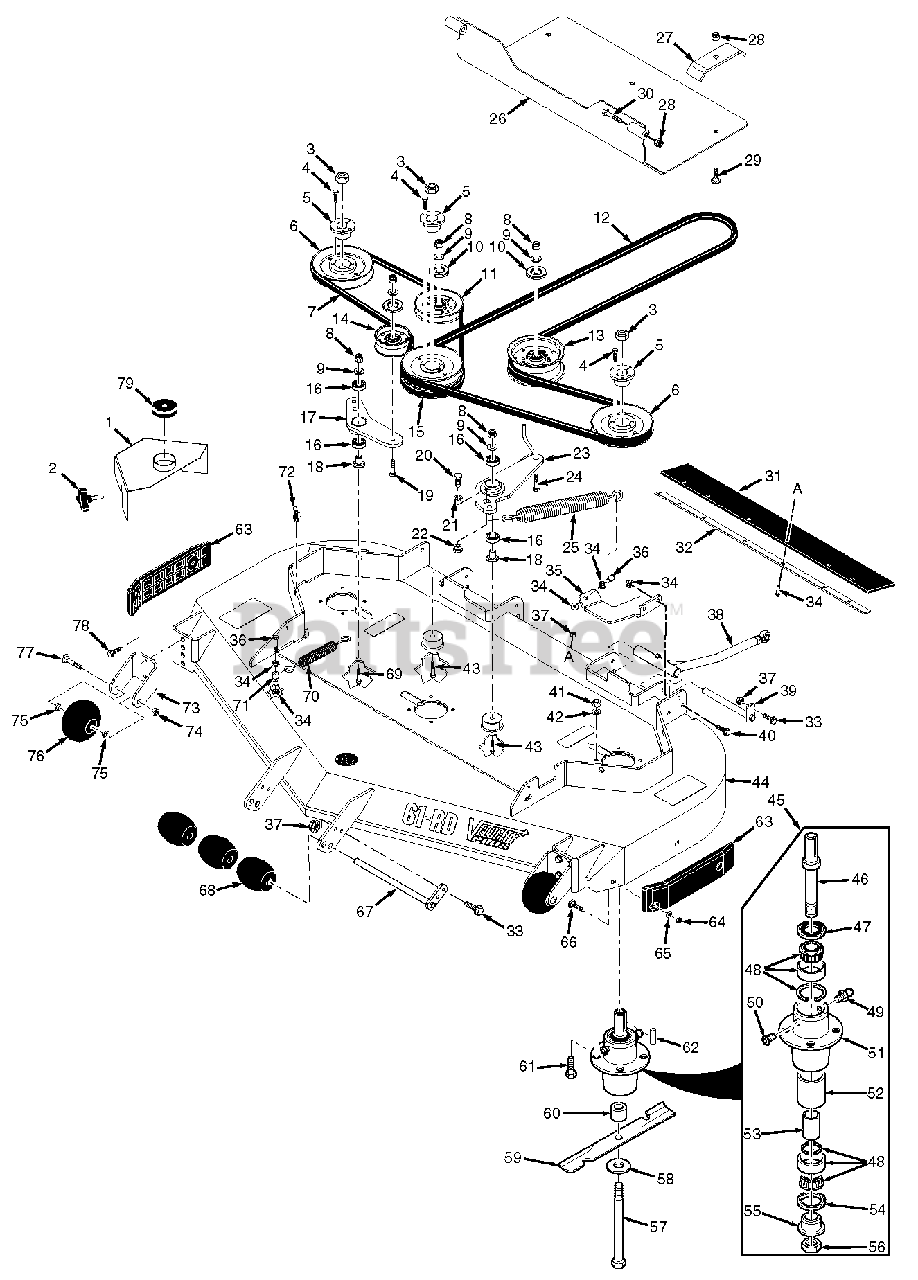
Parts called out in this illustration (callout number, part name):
1	Grip, Deck Latch
2	Deck Latch Assembly w/Grip
3	Spacer, Deck Latch
4	Spring, Torsion Return Lever
5	Ring Pin Assembly w/Lanyard
6	Adjustment Bracket, Upper Cut Height
7	Adjustment Bracket, Lower Cut Height
8	Slide, Height Adjustment
9	Pin, Deck Lift
10	Retaining Ring, 1/2" External "E"
11	Linkage, Deck Lift
11	Rod End, 1/2-20 RH Female
11	Rod End, 1/2-20 LH Female
11	Nut, 1/2-20 UNF Jam
11	Nut, 1/2-20 UNF LH Jam
12	Bolt, Hex Head 1/2-13 x 2"
13	Flatwasher, 1/2-.531 X 1.062 X .095
14	Bolt, Hex Head 5/16-18 x 1"
14	Lockwasher, 5/16" Spring
15	Capscrew, 5/8-11 x 1-1/2"
16	Lockwasher, 5/8" Spring
17	Nut, Serrated Flange 5/16-18
18	Nut, Serrated Flange 3/8-16
19	Nut, Elastic Stop 3/8-16
20	Bolt, Hex Head 3/8-16 x 2-3/4"
21	Bolt, Hex Head 3/8-16 x 1-1/2"
22	Nut, Elastic Stop 1/2-13
23	Spring, Deck Lift
24	Pedal, Foot Lift
25	Stud, 5/8-11 x 22"
26	Swivel Joint, LH
27	Swivel Joint, RH
28	Nut, 5/8-11 UNC
29	Nut, Serrated Flange 3/8-16
30	Chain
31	Grease Fitting, 1/4-28 Self Tap
32	Flatwasher, 5/8"
33	Cotter Pin, 3/16 x 1"
34	Bolt, Hex Head 3/8-16 x 1-1/2"
35	Bolt, Carriage 7/16-14 x 1-1/4"
36	Flatwasher, 7/16-.500 x 1.25 x .083
37	Nut, Elastic Stop 7/16-14
38	Pin, Locking
